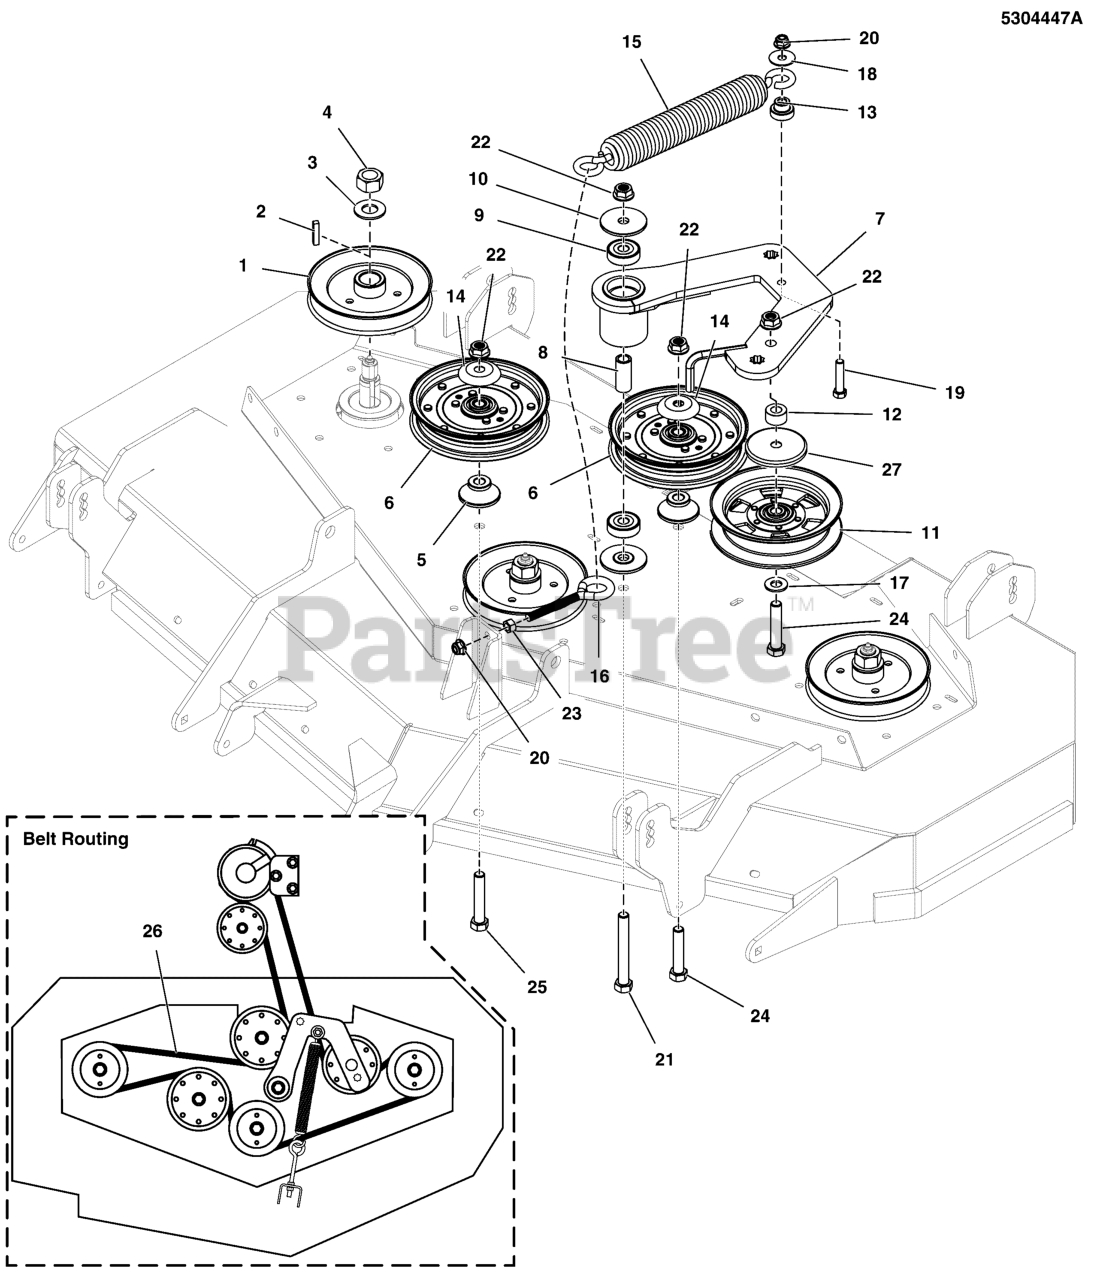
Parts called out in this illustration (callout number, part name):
1	PULLEY, 5.926OB X .985ID, SINGLE B-SEC
2	KEY, 1/4 SQ X 1-1/4
3	WASHER, 3/4 BELLEVILLE CL/ZC
4	NUT, 3/4-16 HEX
5	IDLER MOUNT, .88 HIGH
6	PULLEY, FLT IDLR, 6.0 X 1.0 X .50, CZ
7	WELD, IDLER ARM, IS2600Z-52" - BLK
8	SPACER, .510 X .750 X 1.749, CZ
9	BEARING, 6203-1/2", SEALED
10	SPACER, IDLER ARM, 1/2 X 2.25
11	PULLEY,IDLER,BACKSIDE,NOSEAM 6.25ODX.5ID
12	SPACER, .52 X 1.00 X .56, PM, CZ
13	SPACER, .38 X 1.13 X .781 STEP, CZ
14	SHIELD, PULLEY BEARING, CZ
14	SHIELD, BEARING, 1/2 ID X 2-7/8 OD, CZ
15	SPRING, EXT, 1.5ODX12.25X.234WIRE BLK
16	EYEBOLT, 3/8-16 X 4, 2.13THRD, .75EYE, C
17	WASHER, 1/2 SAE
18	WASHER-3/8 FENDER
19	BOLT, 3/8-16 X 1-3/4" GD5 CZ
20	NUT, 3/8-16 HEX NYLOCK FLANGE
21	BOLT, 1/2-13 X 4" GD5 CZ
22	NUT, Hex Flange, Nylock, 1/2-13
23	NUT, 3/8-16 HEX
24	BOLT, 1/2-13 X 2-1/2" GD5 CZ
25	BOLT, 1/2-13 X 2-3/4 GD5 CZ
26	BELT, SPB/XPB 193.9" EL, LRG ARAMID, 2T
27	SHIELD, BEARING, 1/2 ID X 2-7/8 OD, CZ
